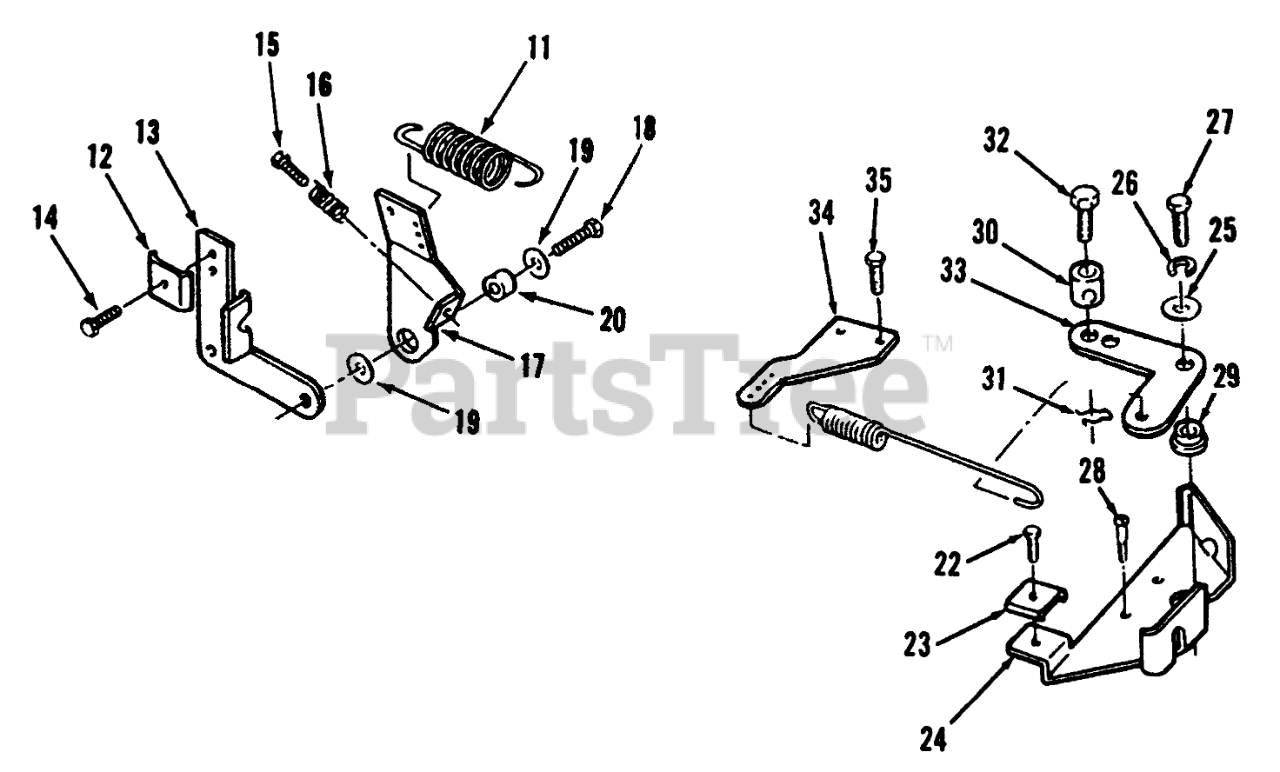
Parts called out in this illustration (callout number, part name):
11	Spring
13	BRACKET
14	Bolt
15	SCREW-TAP
16	Spring
17	GOVERNOR CONTROL ARM
18	SCREW-HWH
19	Screw
20	Bushing
22	TAPPING HEX HD CS
24	BRKT-GOVERNOR CONTRL
25	WASHER-FLAT
26	WASHER-LOCK, SPRING
27	SCREW - CAP HEX HEAD
28	HEX HD CAP SCREW
29	BUSHING-GOV CONTROL
30	Oil Seal
31	PIN-COTTER
32	Bolt
33	LINK-GOV CONTROL
34	ADAPTER-GOV ARM
35	SCREW-TAPPING PAN HD
